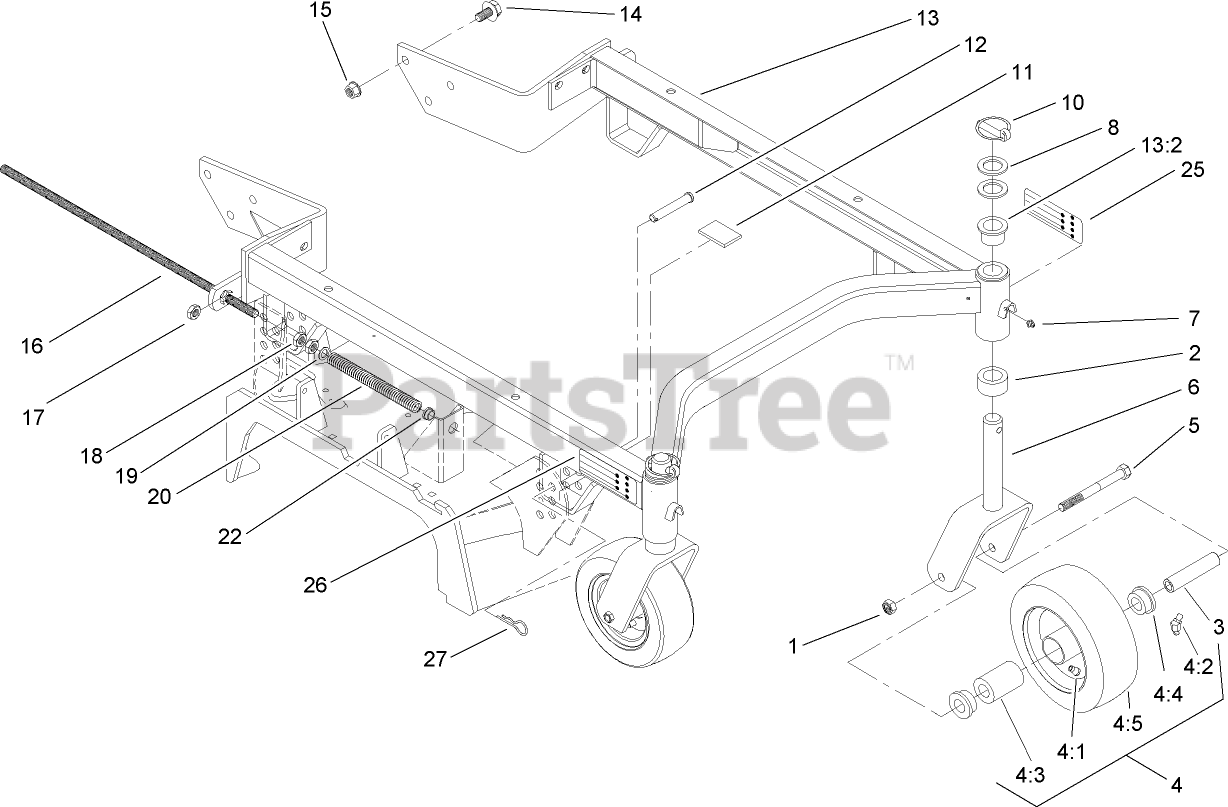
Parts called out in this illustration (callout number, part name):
1	NUT-HEX
2	SPACER-CASTOR
3	BUSHING-SPANNER
4	CASTER WHEEL ASM
4:1	STEM-VALVE
4:2	FITTING-LUBE, 45 DEG
4:3	BEARING
4:4	BEARING-OUTSIDE
4:5	TIRE-TUBELESS
5	SCREW-HH
6	CASTOR FORK ASM
7	FITTING-GREASE
8	WASHER-THRUST
10	PIN-LYNCH
11	CUSHION-RUBBER
12	PIN-CLEVIS
13	FRAME ASM
13:2	BUSHING
14	SCREW-HHF
15	NUT-HF
16	SHAFT-ADJUSTING
17	NUT-LOCK, NI
18	NUT-JAM
19	WASHER
20	SPRING
22	BUSHING-FLANGE
25	DECAL-HOC, LH
26	DECAL-HOC, RH
27	PIN-HAIR
